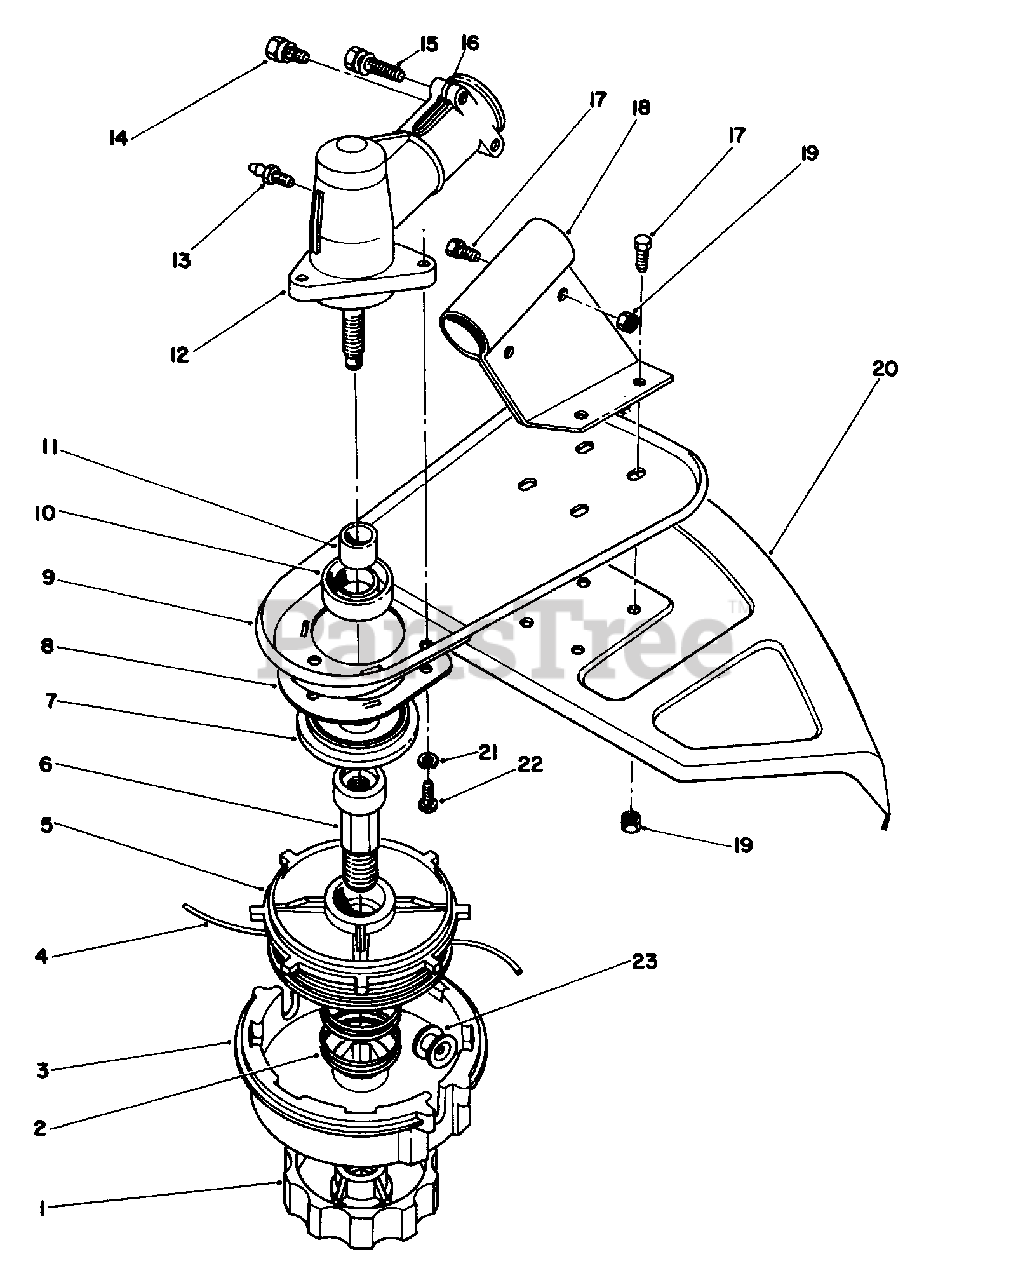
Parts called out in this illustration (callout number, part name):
1	Knob-L.H.
3	Housing-Spool
4	.080 Line (38 ft.)(Optional)
5	Spool-Inner
7	Dust Cap
8	Guard-Grass Wrap
9	Support-Shield
10	Seal, Oil
11	Sleeve-Spline
12	Gear Box Assembly (Incl. Ref. #10, 11, & 13-16)
13	Fitting-Grease
14	Hex Hd. Machine Screw
15	Hex Hd. Machine Screw
17	Hex Hd. Machine Screw
18	Bracket-Shield
19	Locknut
20	Shield-Grass
21	Lockwasher
22	Screw-Guard
